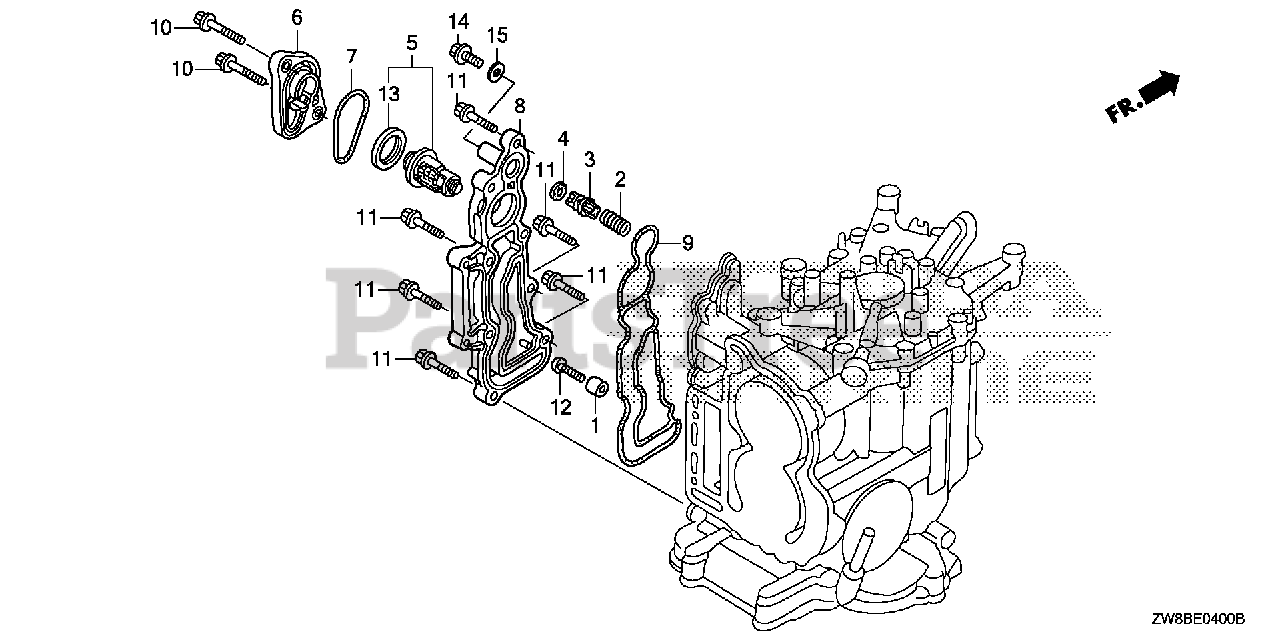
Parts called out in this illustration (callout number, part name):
1	METAL, ANODE
2	SPRING, FLUSH VALVE
3	VALVE, FLUSH
4	GASKET, FLUSH VALVE
5	THERMOSTAT ASSY.
6	COVER, THERMOSTAT
7	O-RING, THERMOSTAT COVER
8	COVER, WATER JACKET
9	GASKET, EX. WATER JACKET COVER
10	BOLT, FLANGE (6X36) (CT200)
10	BOLT (6X36) (CT200)
11	BOLT, FLANGE (6X22) (CT200)
12	BOLT, FLANGE (5X20)
12	SCREW, PAN (5X20)
13	RUBBER, RING
14	BOLT, SPECIAL (8MM)
15	GASKET (8MM)
